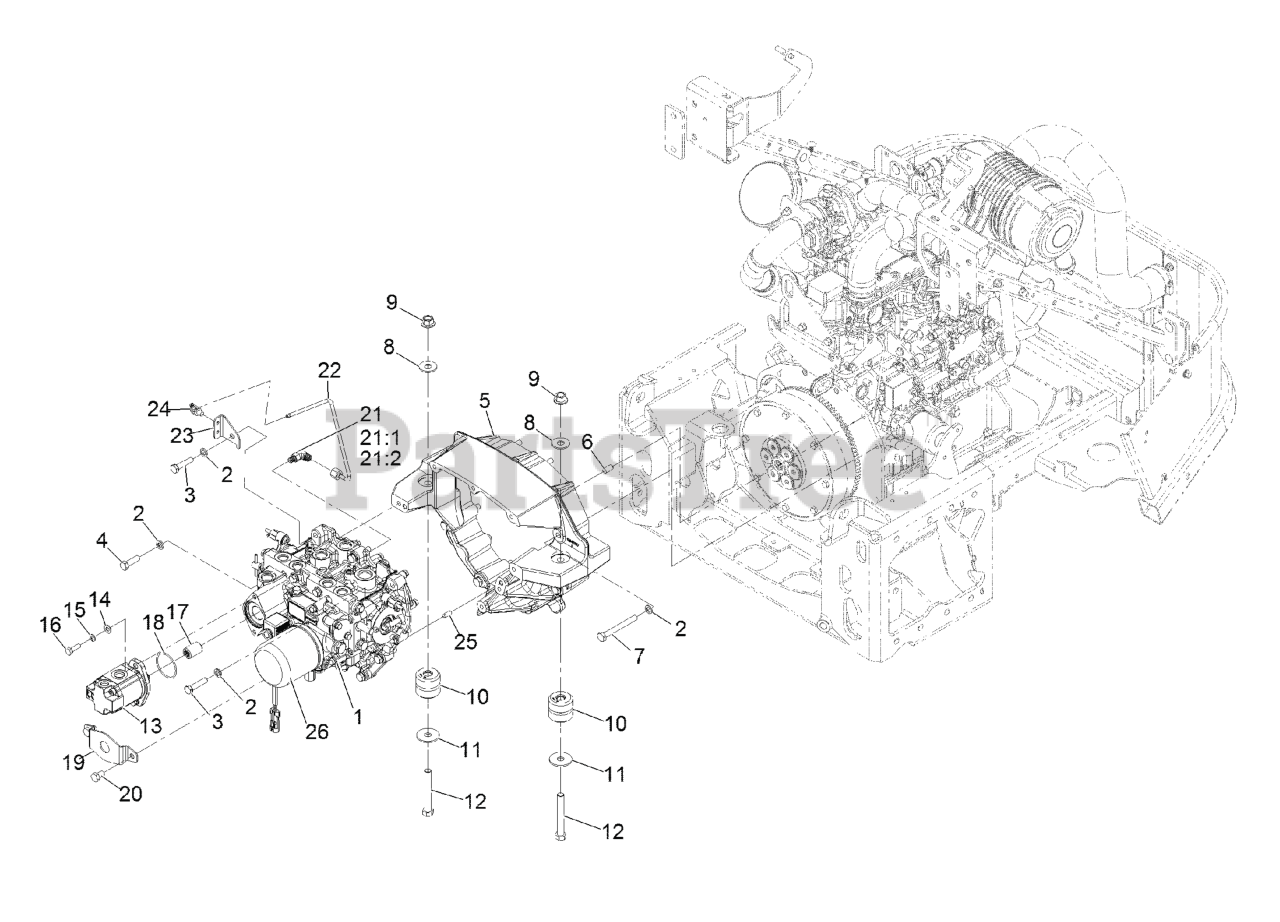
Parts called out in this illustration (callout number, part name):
1	TRANSMISSON ASM
2	WASHER-LOCK
3	SCREW-HH
4	SCREW-HH
5	Housing-Flywheel
6	PIN-DOWEL
7	SCREW-HH
8	WASHER-FLAT
9	Nut-Lock 1/2-13
10	MOUNT-ISOLATOR
11	WASHER-THRUST
12	SCREW-HH
13	HYD GEAR PUMP ASM
14	WASHER-PLAIN
15	WASHER-LOCK
16	SCREW-HH
17	COUPLER-SPLINE
19	SHIELD-SEAL
20	SCREW-HH
21	FITTING-ELBOW, 90 DEG
21:1	O-RING
21:2	O-RING
22	TUBE ASM
23	SUPPORT-TUBE
24	CLIP-TIE
25	PIN-DOWEL
26	FILTER-OIL, HYD
